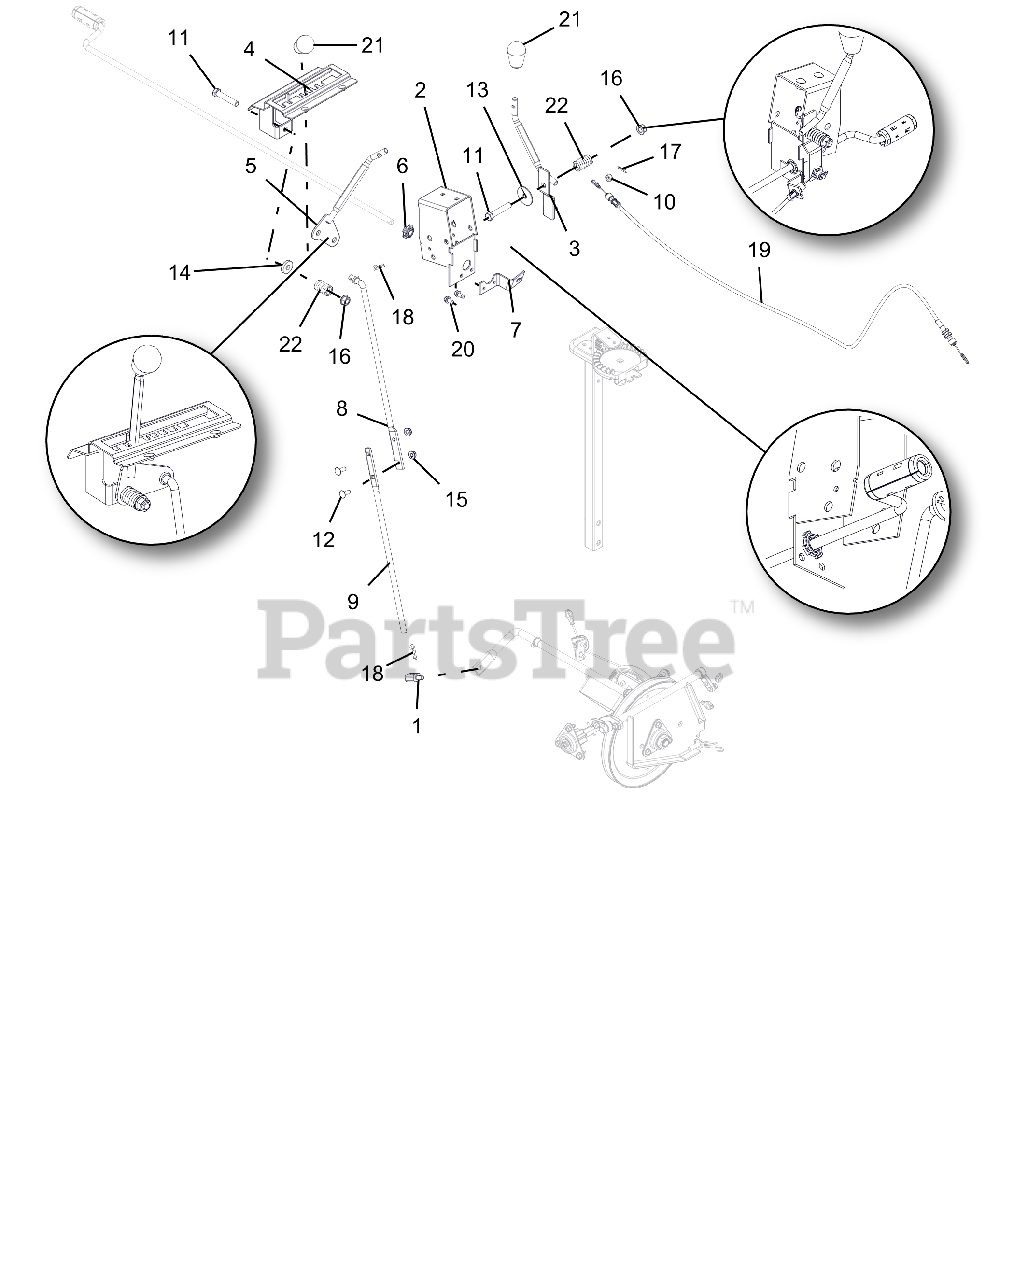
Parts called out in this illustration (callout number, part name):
1	PIVOT,SHIFT ROD .375-16(TRUNN)
2	WELDMENT, BRACKET INTERLOCK
3	WELDMENT, CONTROL LEVER (DEFL)
4	WELDMENT, DETENT PLATE-COMPACT
5	LEVER, CONTROL-SHIFT(WELDMENT)
6	CRANK BUSHING, NYLON CHUTE BK
7	ANCHOR, DEFLECTOR CABLE
8	ROD, SHIFT - UPPER
9	ROD, SHIFT - LOWER
10	BSHG-SLV .265X.500X.219
11	@BLT-HEX .38-16X2.00 GR5 YWZC
12	@BLT-RDHDSQNK .25-20X.75 G5YZ
13	WSHR-FL-STL .380X1.50X.062 YWZ
14	WSHR-FL-STL .406X1.00X.188 YWZ
15	@NUT-LK-CTR-FLG .25-20 YWZC
16	@NUT-LK-TOP-FLG .38-16 YWZC
17	PIN-HAIR INT .06X.18X.77
18	PIN-HAIR INT .08X.18X1.18 YWZC
19	CABLE, DEFLECTOR CAP SNO-TEK
20	SCR-TAP .25-20X.50 HWH TR YWZ
21	KNOB,SOFT TEARDROP,PUSH-ON BLK
22	SG-COMP .125X.781X1.250
